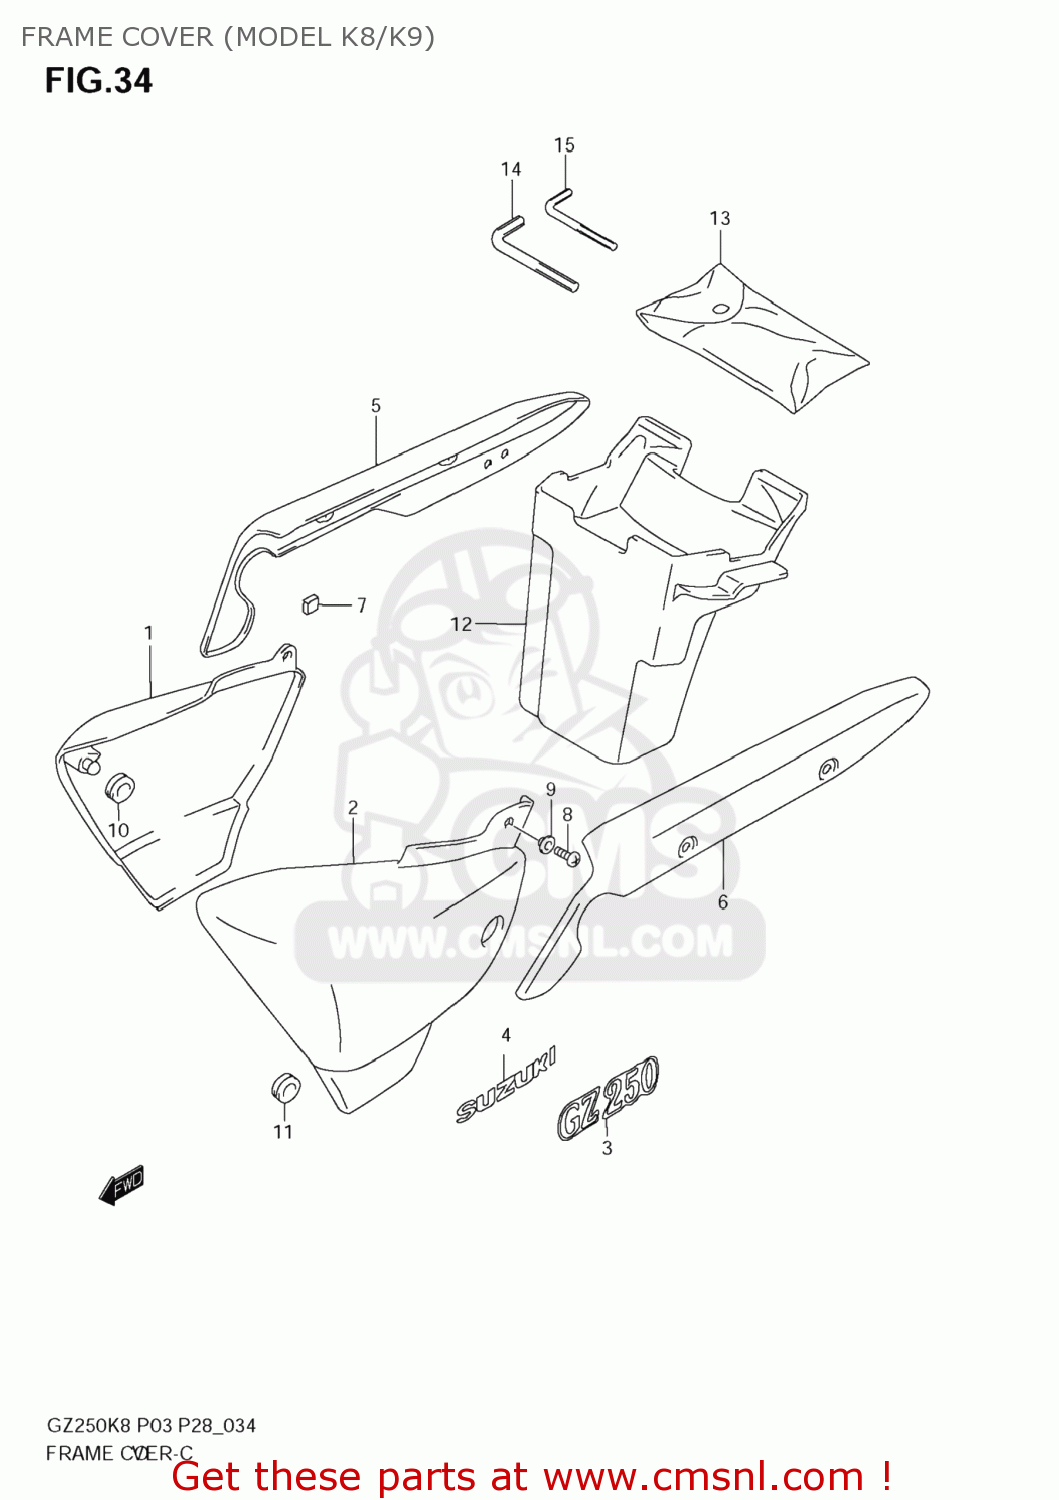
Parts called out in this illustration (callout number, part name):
1	COVER,FRAME
2	COVER,FRAME
3	EMBLEM,FRAME CO
4	EMBLEM,SUZUKI
5	COVER, FRAME REAR RH
6	COVER, FRAME REAR LH
7	CUSHION
8	SCREW
9	WASHER
10	CUSHION
11	CUSHION
12	BODY, LUGGAGE BOX
13	TOOL ASSY
14	SPANNER,HEXAGON(6)
15	SPANNER,HEXAGON(4)
